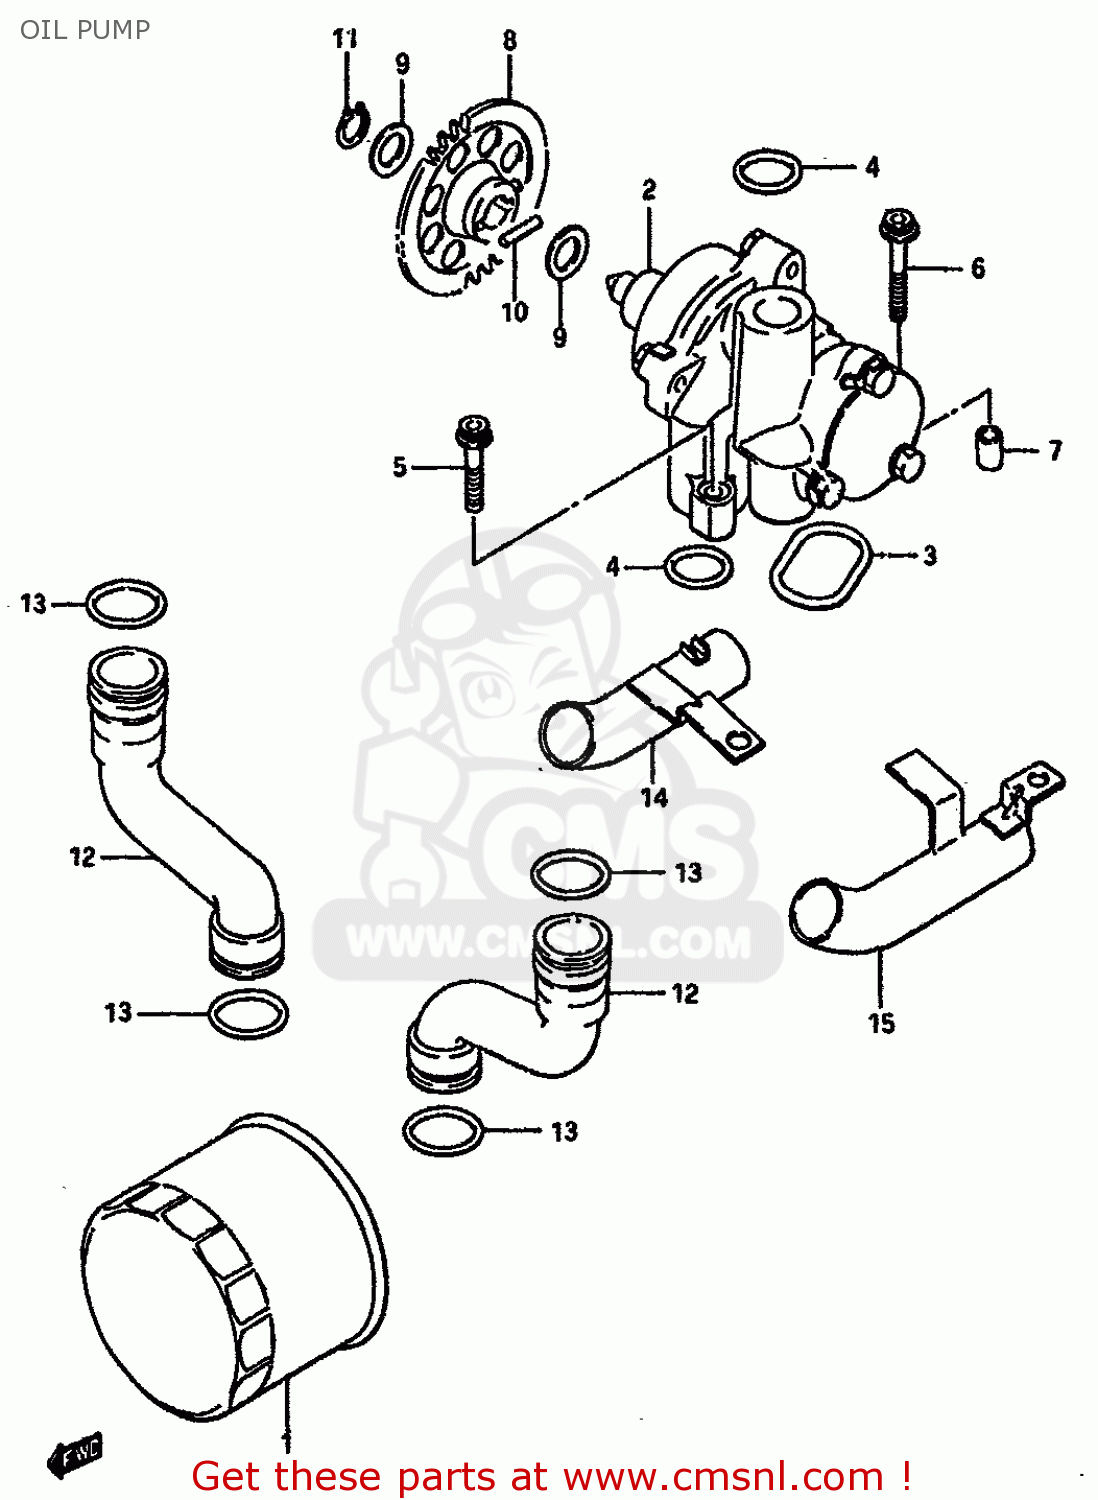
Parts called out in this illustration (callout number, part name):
1	FILTER ASSY,ENGINE OIL
2	PUMP ASSEMBLY,OIL
3	O RING,OIL PUMP
4	O RING(D:3.2,ID:17.8)
5	BOLT
6	BOLT
7	PIN
8	GEAR,OIL PUMP DRIVEN
9	SHIM
10	PIN(5X18)
11	CIRCLIP
12	HOSE,OIL
13	O-RING
14	PIPE,OIL,OUTLET,UNDER
15	PIPE,OIL,OUTLET,UNDER
